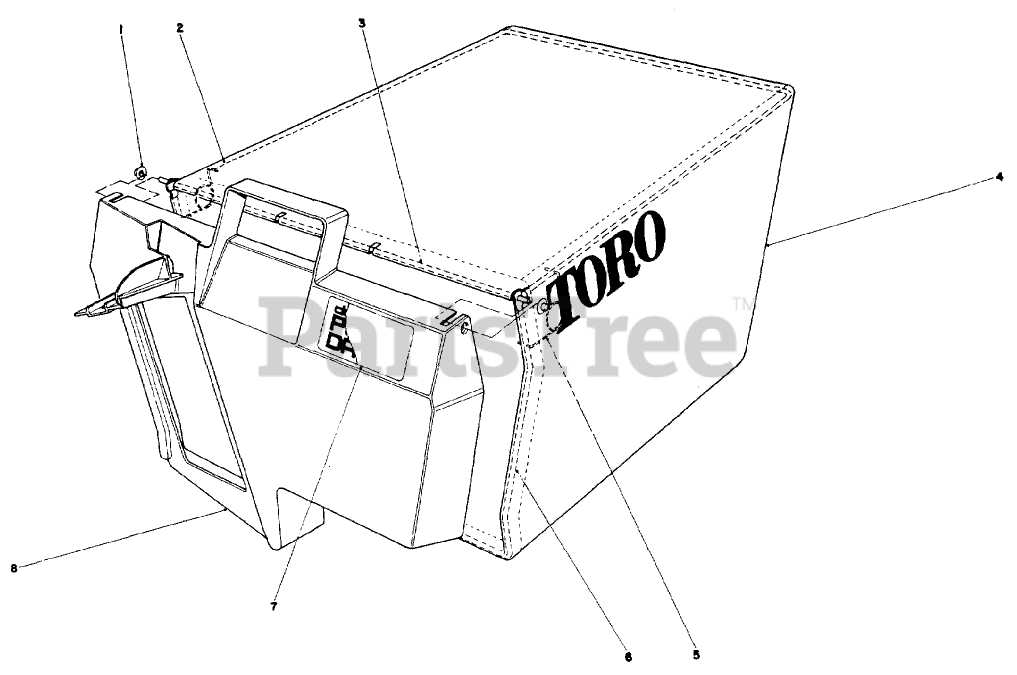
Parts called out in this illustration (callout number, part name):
1	NUT-PUSH
3	HingeBag Door
5	SPRING
6	FRAME-BAG
